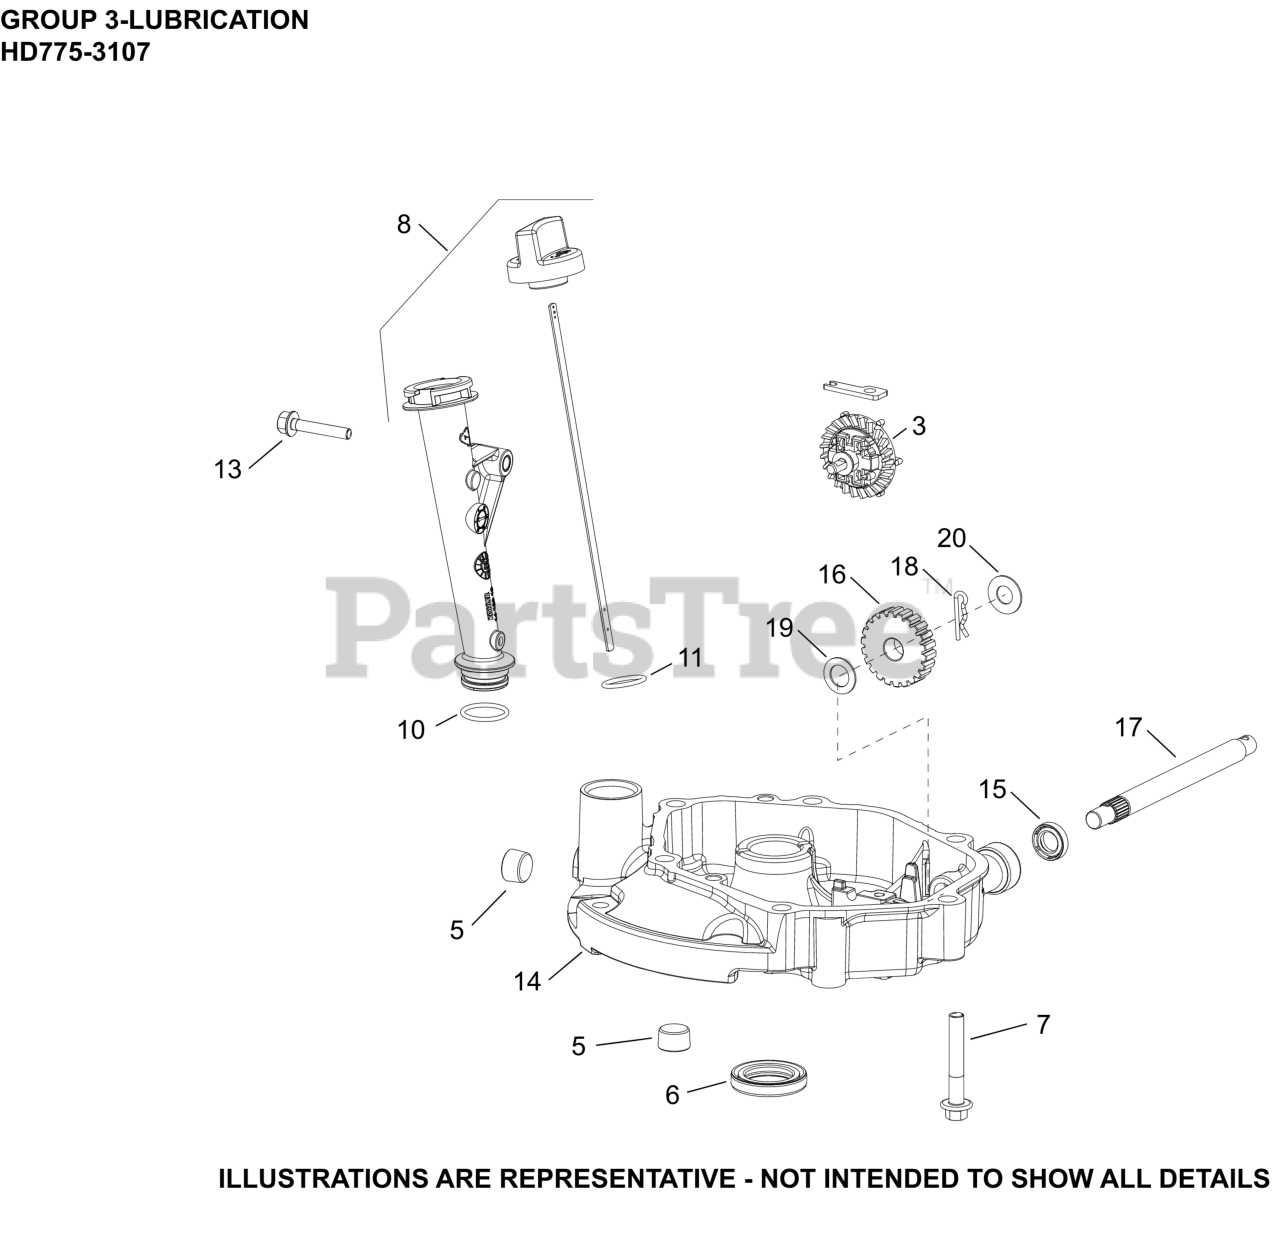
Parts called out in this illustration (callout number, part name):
3	GEAR ASSEMBLY, GOVERNOR
5	PLUG, PIPE (W/SEALANT)
7	SCREW, HEX FLANGE (M8)-USE 25 086 456-S
8	TUBE ASSEMBLY OIL FILL-USE 14 123 20-S
10	O-RING, OIL FILL TUBE
11	O-RING (CAP)
13	SCREW, HEX FLANGE (M6)-(#25086435S)
14	KIT, OIL PAN
15	SEAL, OIL
16	GEAR, 2ND PTO
17	SHAFT, DRIVE SECOND PTO
18	CLIP, GOVERNOR ARM
